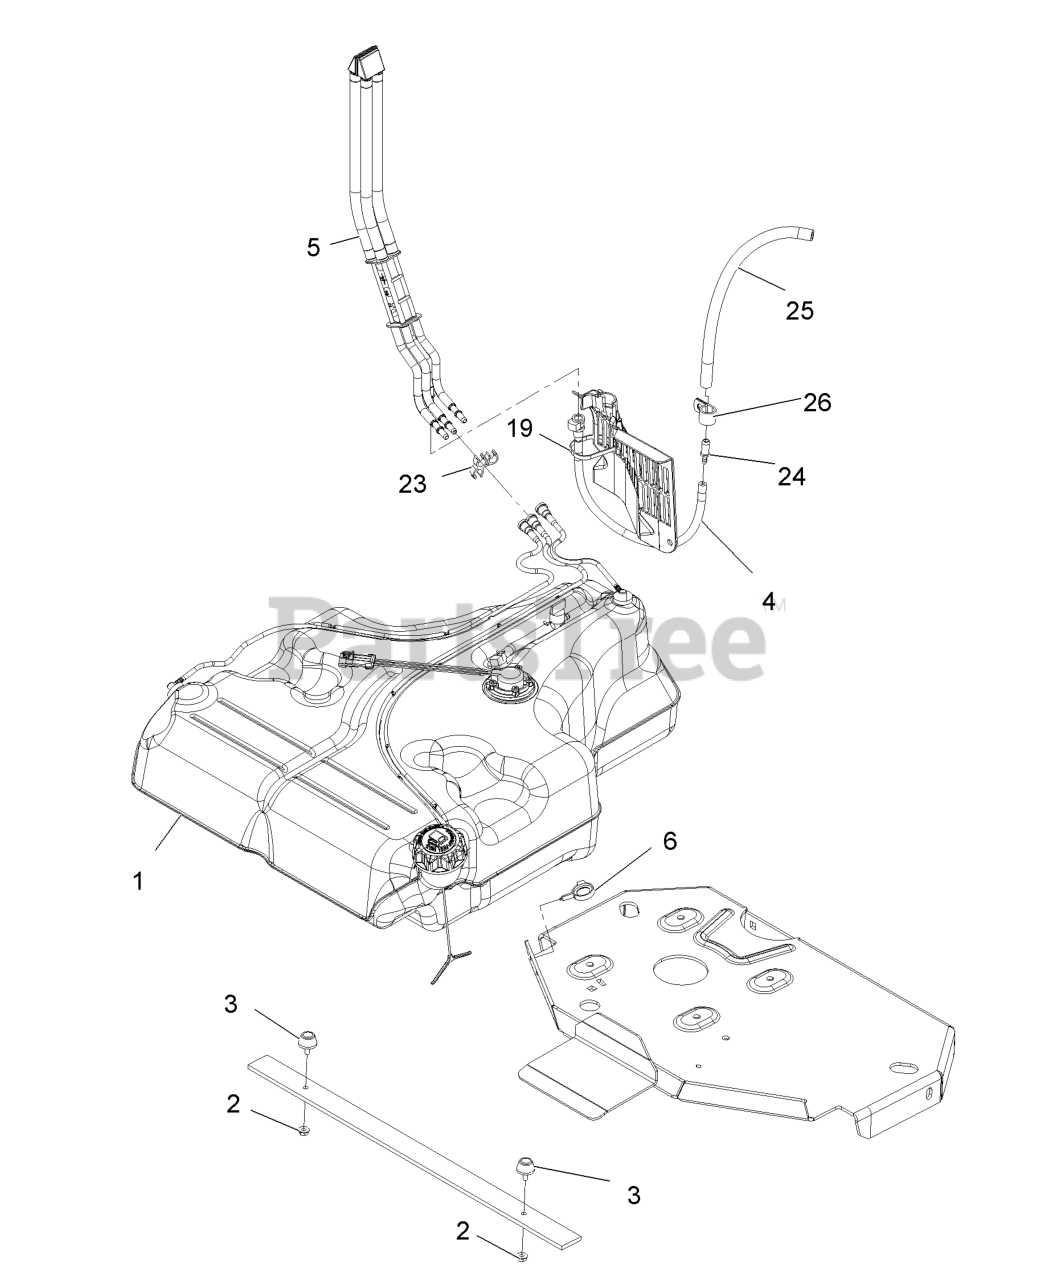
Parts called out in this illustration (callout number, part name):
3	BUMPER-RUBBER
4	HOSE ASM
5	FUEL MANIFOLD VENT ASM
6	CLAMP-HOSE
19	TIE-PLASTIC
23	CLIP-SPACER
24	FITTING-STRAIGHT
25	HOSE-FUEL
26	CLIP-LOOM
